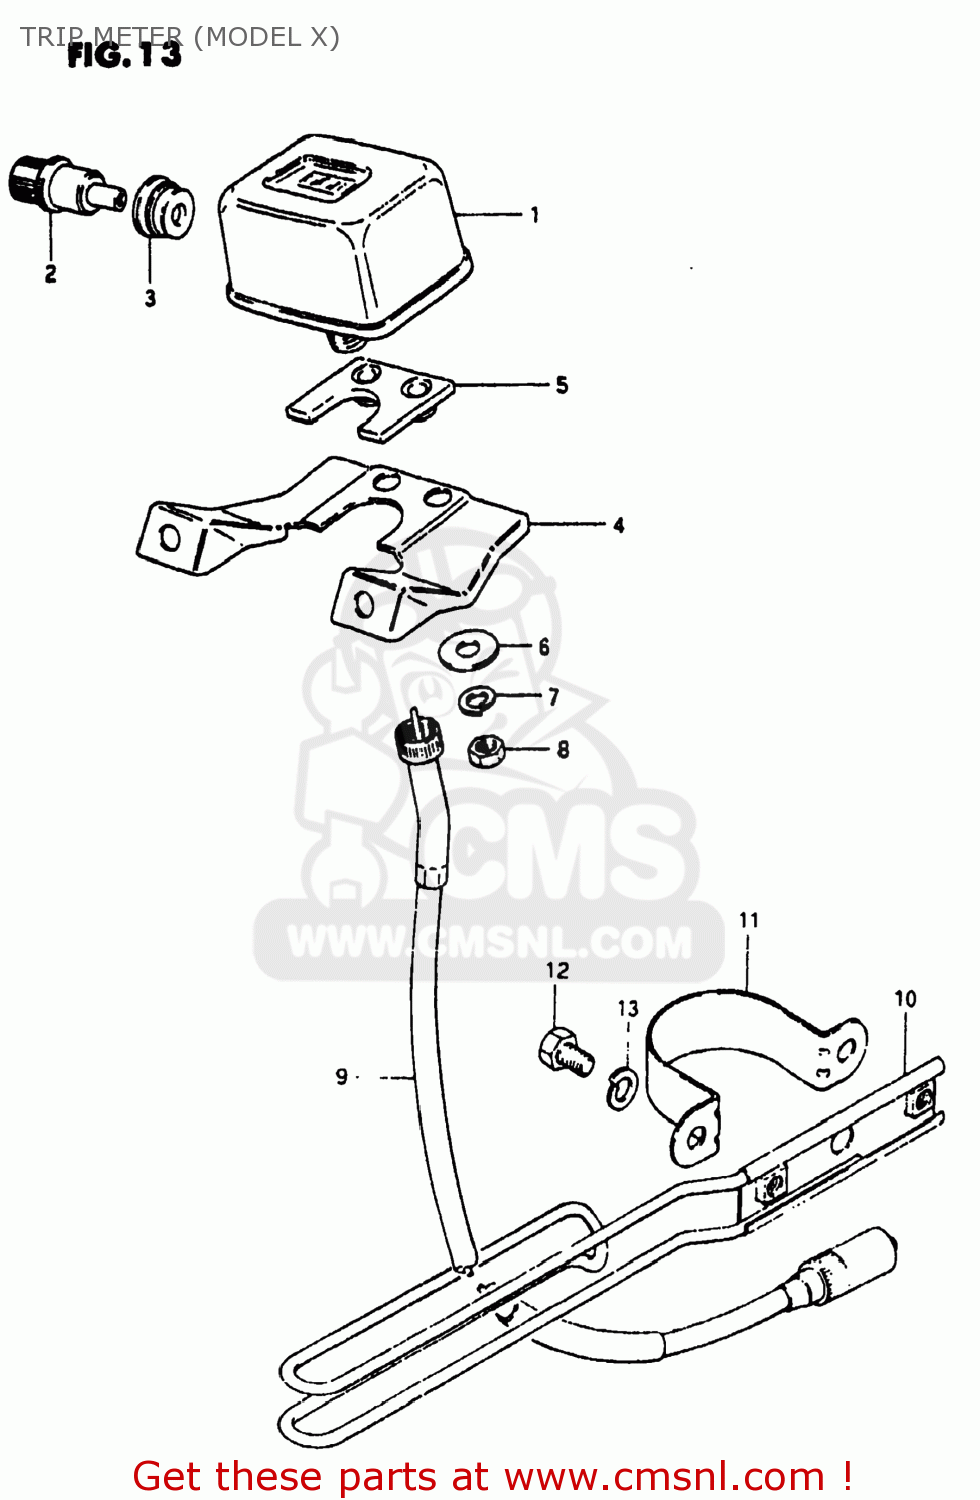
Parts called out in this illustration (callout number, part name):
1	TRIP METER
2	KNOB,TRIP METER
3	COVER,TRIPMETER KNOB
4	BRACKET,TRIPMETER
5	CUSHION,TRIPMETER
6	WASHER,METER
7	LOCK WASHER
8	NUT
9	CABLE ASSEMBLY,SPEEDOMETER
10	CLAMP,SPEEDOMETER CABLE
11	CLAMP
12	BOLT
13	LOCK WASHER
